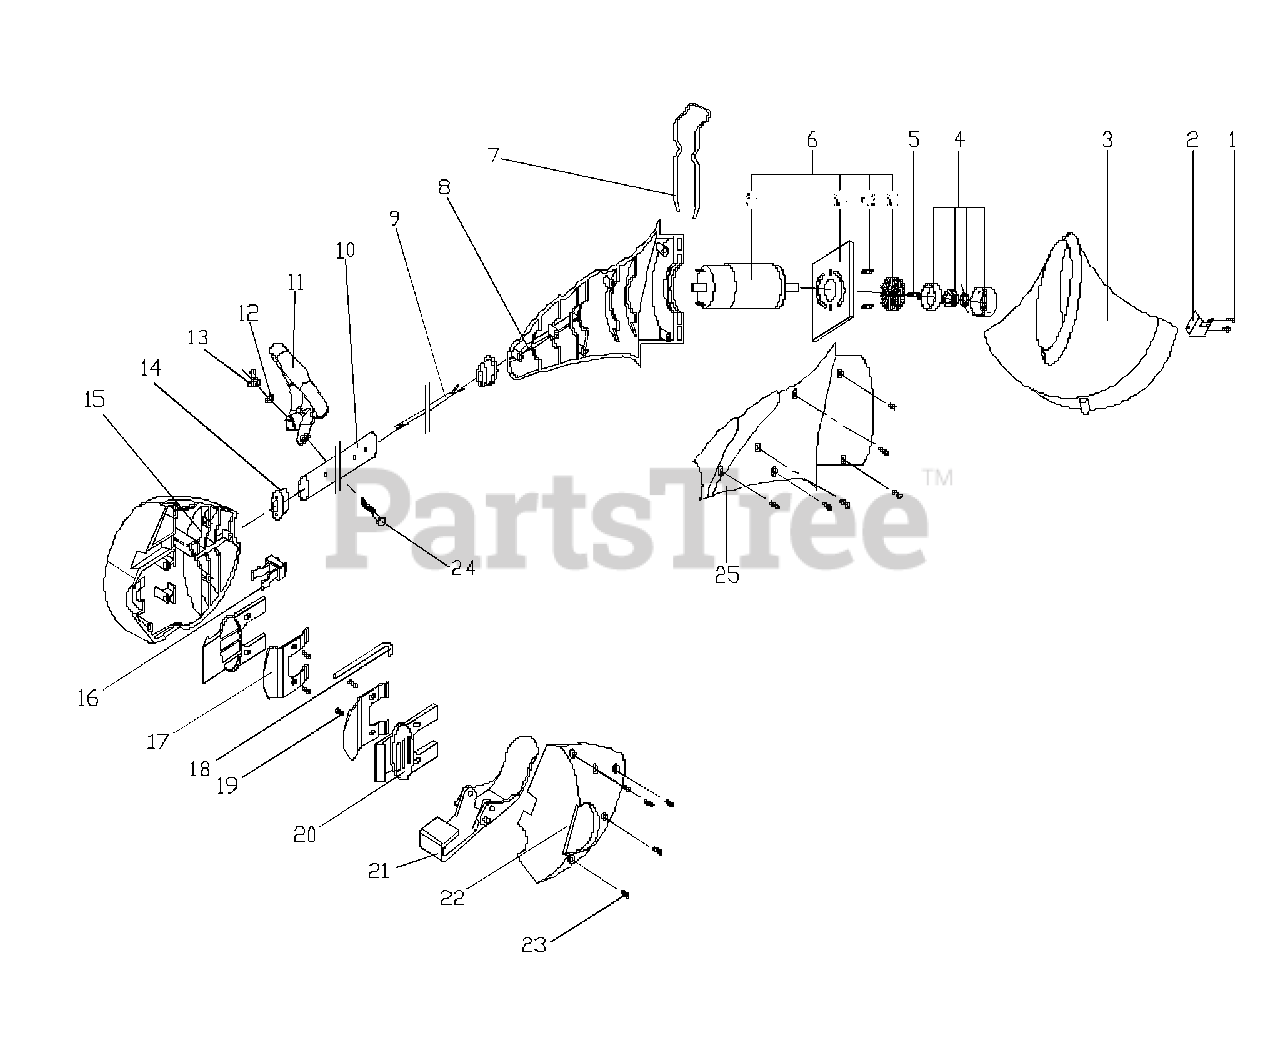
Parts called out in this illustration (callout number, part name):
4	SPOOL ASS'Y
6	MOTOR ASS'Y
6	SCREW
6	FIX PLATE
8	HOUSING (L)
15	CONNECT (L)
16	TERMINAL ASS'Y
17	SPRING LAMINATION
22	CONNECT (R)
25	HOUSING (R)
